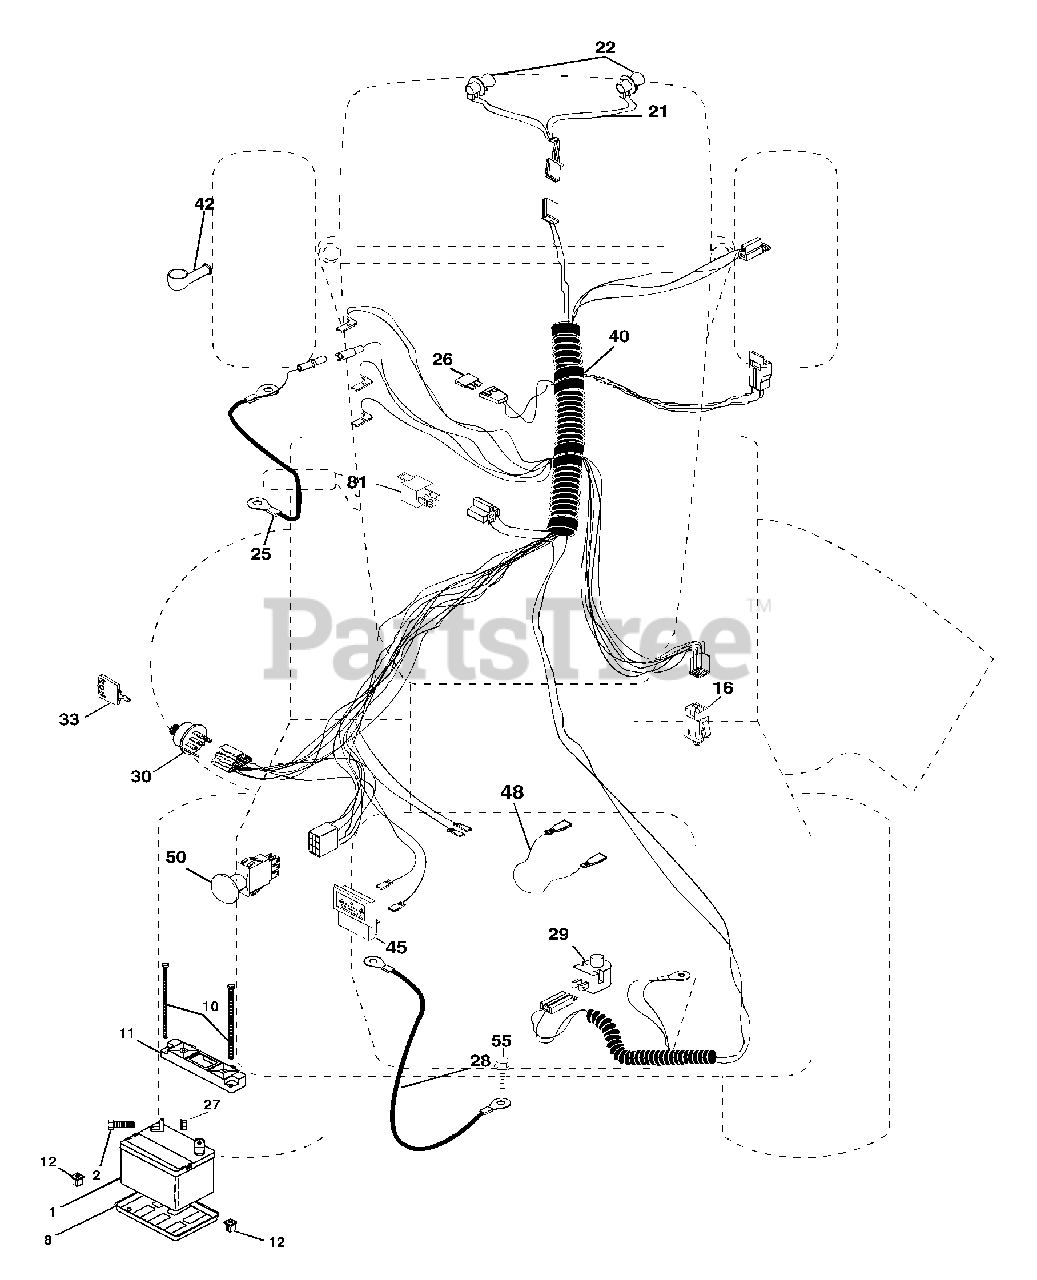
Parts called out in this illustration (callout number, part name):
1	Battery
2	Bolt Hex Hd 1/4-20 Unc x 3/4
8	Tray, Battery
10	Bolt, BTR FRT 1/4-20 x 7.5
11	Hold Down Battery, Front
12	Nut, Push, Nylon
16	Switch Interlock Push-In
21	Harness Asm Light W/Bulbs
22	Bulb Light
25	Cable Batterywire
26	Fuse
28	Cable Ground
29	Switch Plunger Normal OP Olive
30	Switch Ign 4 pos w/lights
33	Key Ign
40	Harness Ign.
42	Cover Terminal Red
45	Ammeter Rectangular
48	Protection Wire Loop
50	Switch, PTO
55	Screw Thdrol 5/16-18 x 1/2
79	Bulbholder
81	Relay Asm
